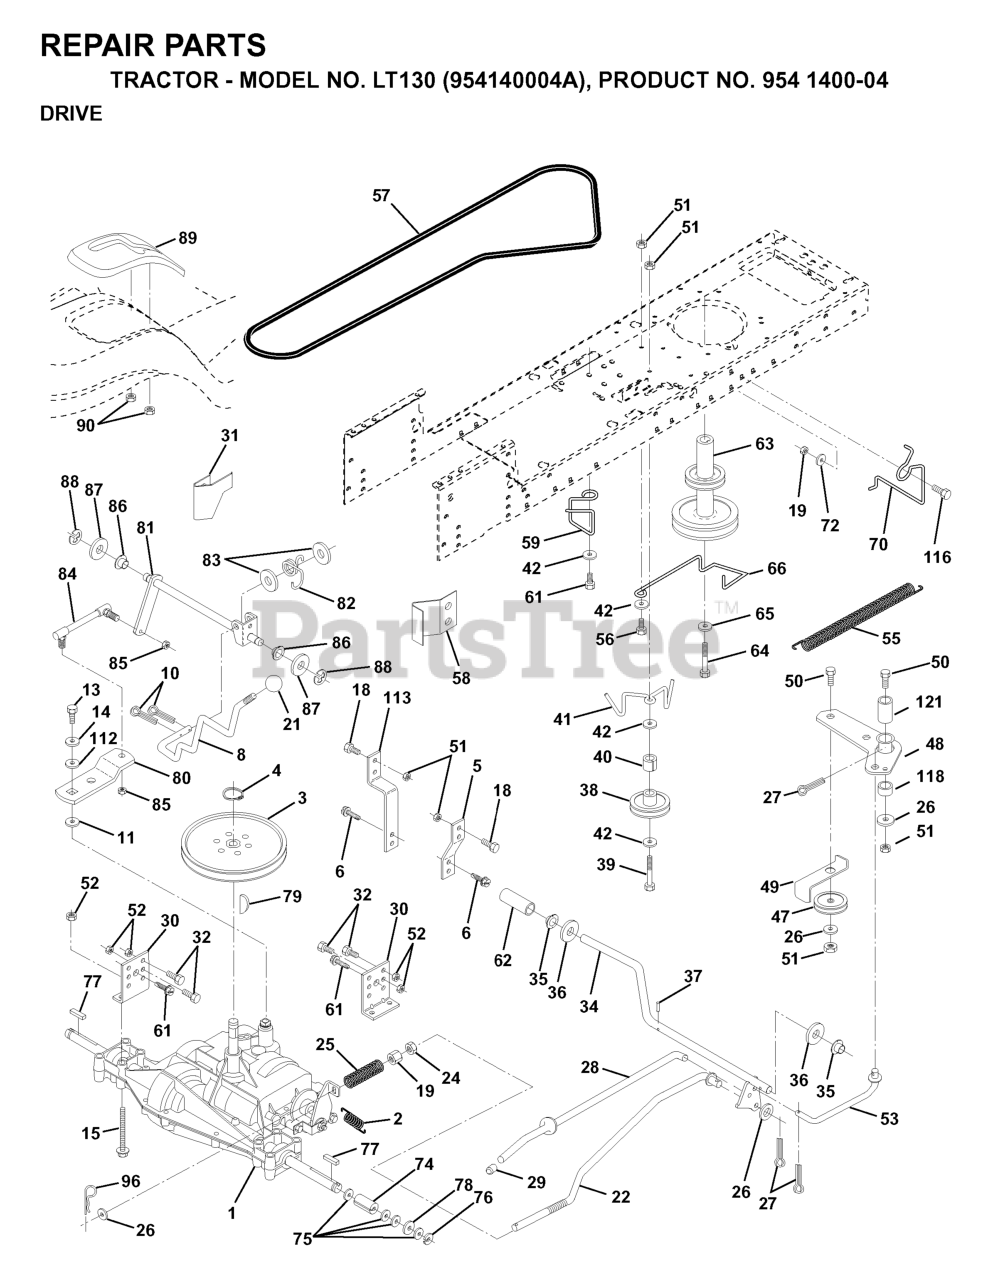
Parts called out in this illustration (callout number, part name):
2	SPRING,BRAKE RETURN
3	PULLEY TRANS
4	RETAINING RING LT
5	STRAP TORQUE
6	SCREW.THDROL.5/16-18X3/4.TTY
8	ROD SHIFT FENDER
10	PIN COTTER
11	WASH-SHFT PLT LT
13	BOLT 1/4-28X3/4
14	LOCKWASHER
15	BOLT HEX 5/16-18 GR 5
19	NUT
21	KNOB.DUCKHEAD.1/2
24	NUT
25	SPRING ROD LT
26	WASHER
27	COTTER PIN
28	ROD BRAKE PARK LT
29	PLUNGER CAP
30	BRACKET TRANSAXLE
31	KEEPER BELT LH
32	BOLT
34	SHAFT, FOOT PEDAL
35	BEARING.NYLON
37	DRIVE PIN
38	PULLEY.IDLER.FLAT
41	KEEPER, BELT IDLER
42	WASHER
47	IDLER PULLEY
48	BELLCRANK ASSEMBLY
49	RETAIN BELT
50	BOLT
52	LOCKNUT
53	LINK, CLUTCH LT
55	SPRING, RETURN LT
57	V-BELT
59	KEEPER CENTER SPAN
61	SCREW
62	PEDAL COVER T
63	PULLEY.ENG.CL.MECH.SLVR.LT/YT
64	BOLT
65	LOCKWASHER
66	KEEPER BELT ENGINE
70	KEEPER BELT ENG
72	WASHER
74	SPACER AXLE
77	SQUARE KEY
79	KEY STD (1373) DANA
81	SHAFT ASM CROSS 20"T
82	SPRING,TORSION
83	WASHER
84	ROD,TIE
85	NUT LOCK CENTER 1/4 -28 FNTHD
86	BUSHING.STEERING.ROD LTB-WSL
89	CONSOLE SHIFT
90	NUT.PUSH.3/16
96	RETAINER M
113	STRAP TORQUE LH LT
116	BOLT
118	SPACER BELLCRANK
121	NYLINER CLUTCHING
